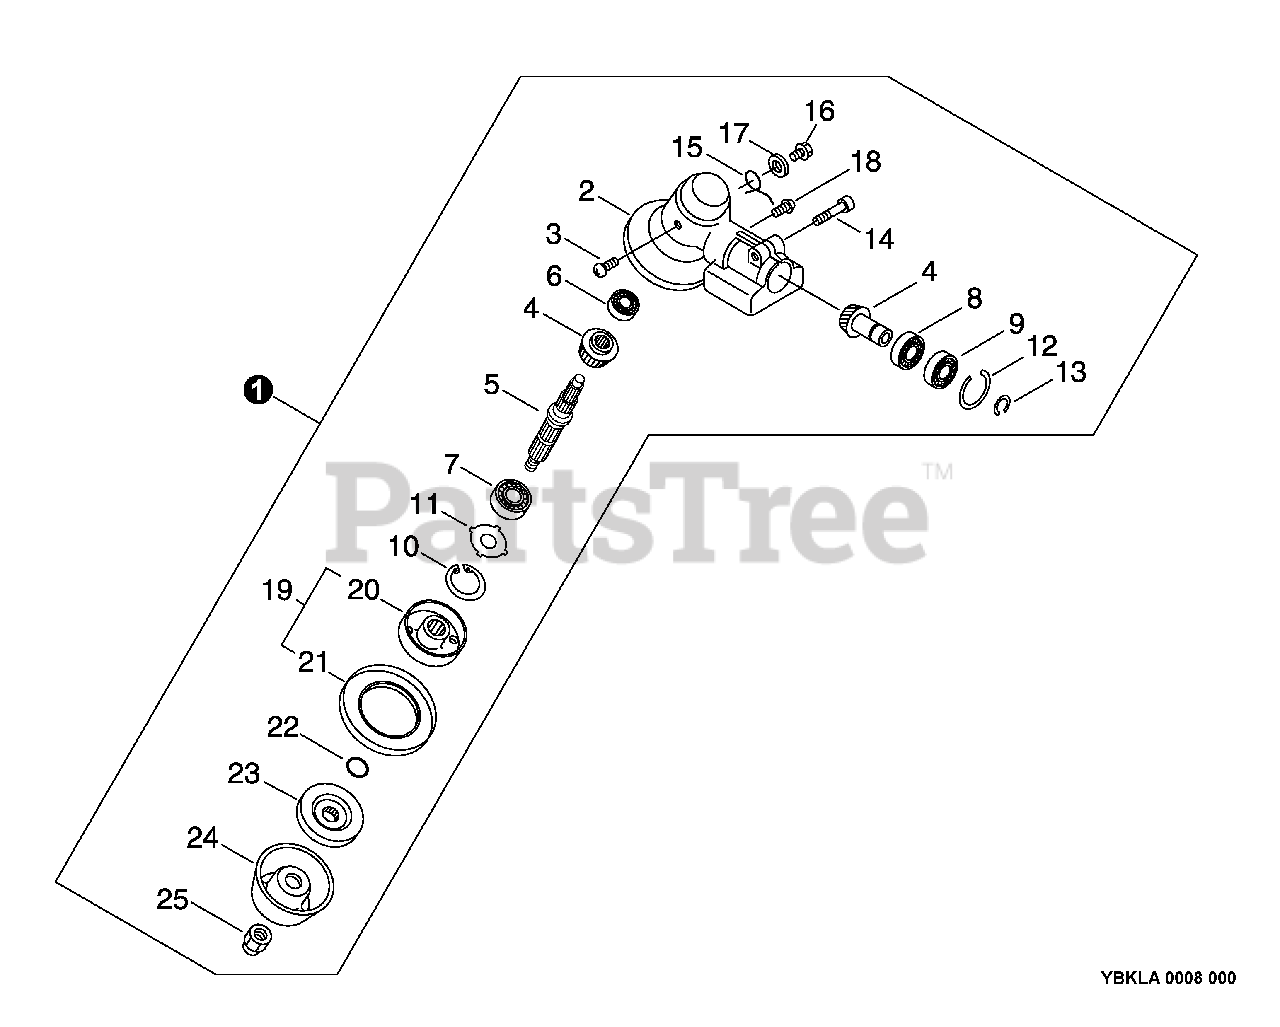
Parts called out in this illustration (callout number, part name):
1	GEAR CASE ASSY
2	CASE, GEAR
3	SCREW 4×6
4	GEAR SET
5	SHAFT, GEAR
6	BEARING, BALL 629
7	BEARING, BALL 6201
8	BEARING, BALL 6001
9	BEARING, BALL 6001Z
10	RING, SNAP Ø32
12	RING, SNAP 28
13	RING, RETAINING - 12
14	BOLT 6×30
15	SPRING, TORSION
16	BOLT M8×8
17	WASHER 8.5×18×0.8T
18	SCREW 5×10
19	RETAINER, BLADE
20	PLATE, ADAPTOR
21	PLATE, ADAPTOR - LOWER
22	O-RING 12 MM
23	PLATE, ADAPTOR - LOWER
25	NUT, LOCK 10 - NYLON INSERT
